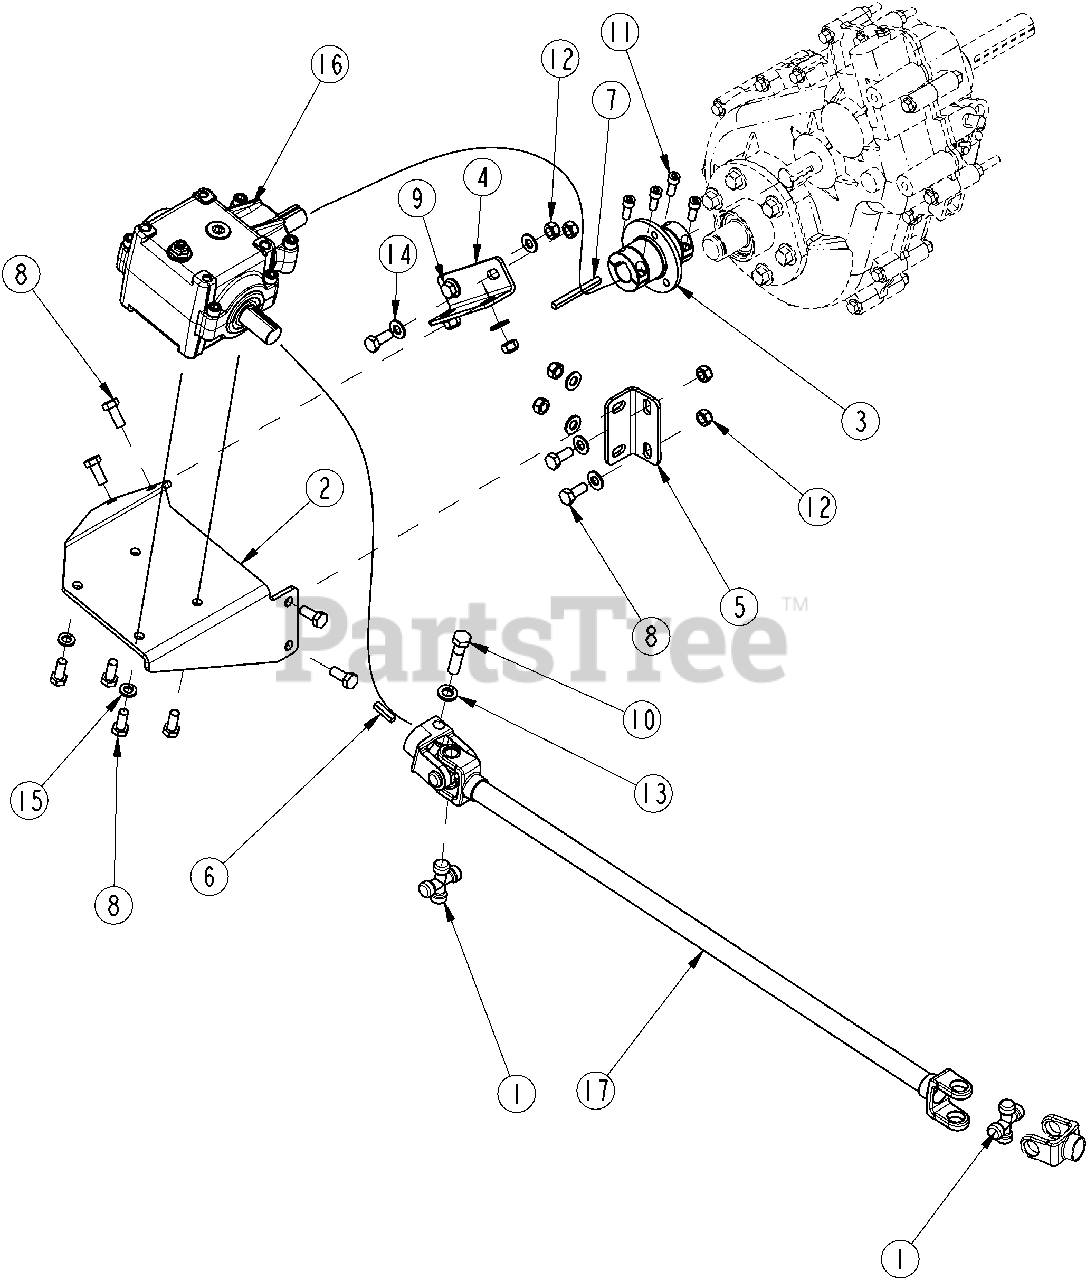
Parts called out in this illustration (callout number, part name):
1	CROSS & BRG KIT
2	GEAR BOX MNT PLATE
3	CLAMP COUPLING
4	MOUNT BRACKET GEARBOX REAR
5	MOUNT BRACKET GEARBOX FRONT
6	KEY 3/16 X 7/8
7	KEY .187 X .187 X 2.25 LG
8	HHCS 5/16-18X3/4 GR5 YELLOW DI
9	HHCS 5/16-18X1 GR5 YELLOW DIE
10	HHCS 3/8-24X1 1/2 GR8 PLT
11	HSHCS 1/4-28X5/8
12	NUT HEX NYLOCK 5/16-18 PLT
13	WASHER LOCK SPRING 3/8 PLT
14	WASHER FLAT 5/16 HARD ASTMF436
15	WASHER LOCK SPRING 5/16 YELLOW
16	GBOX MODEL R100 1.5TO1 RATIO
17	REAR HALF DRIVELINE 4X4 ST
